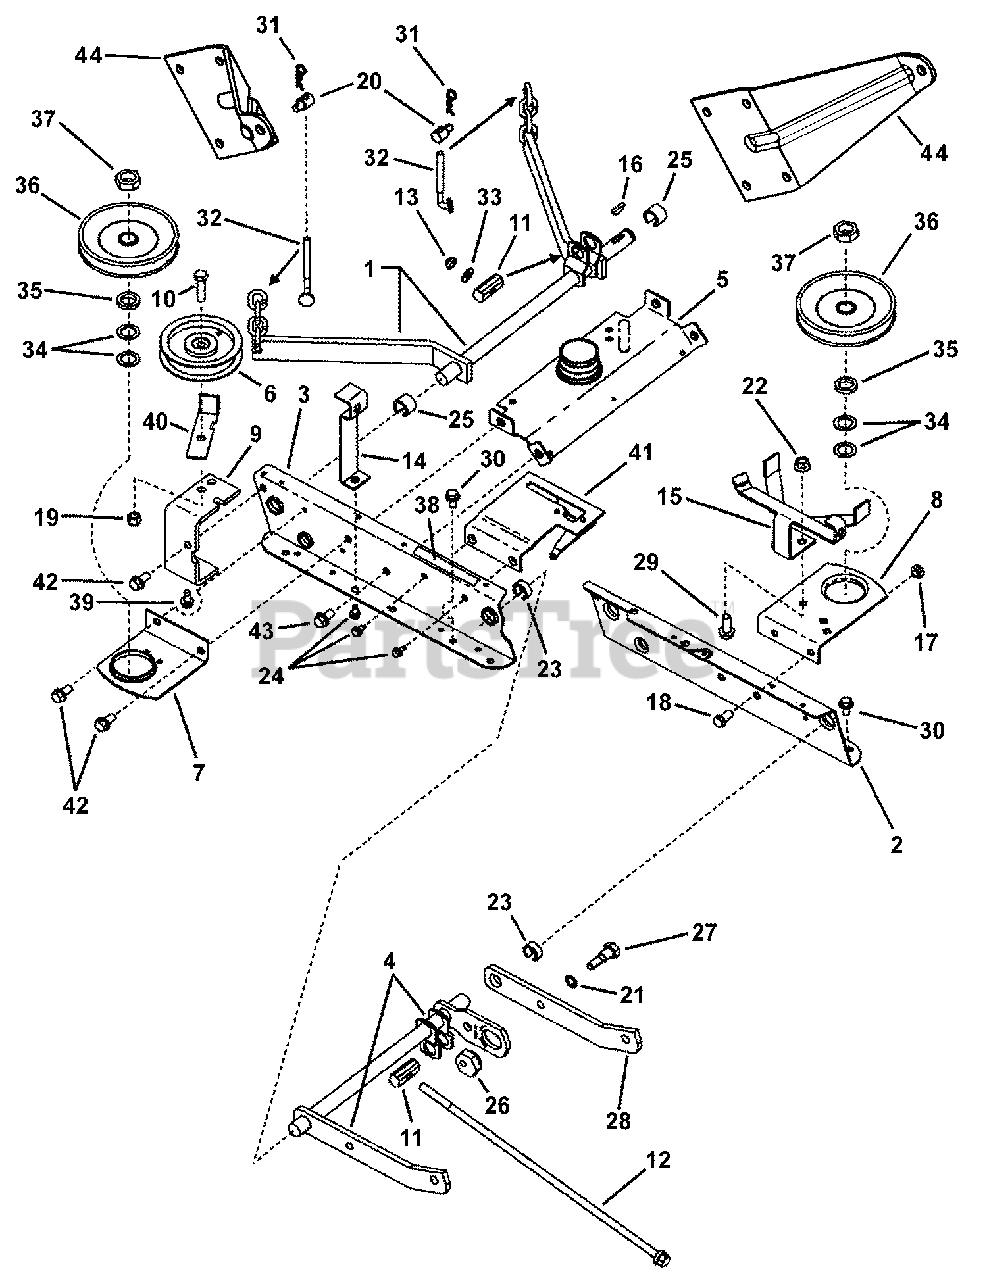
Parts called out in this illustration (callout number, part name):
1	ASSEMBLY, Rear Lift Arm
2	RAIL, Deck Lift, Left Hand
3	RAIL, Deck Lift, Right Hand
4	WELDMENT, Front Lift Arm
5	WELDMENT, Top Brace
6	IDLER, 4-1/8" Flat
7	BRACE, R.H. Spindle
8	BRACE, L.H. Spindle
9	BRACE/IDLER Mounting Bracket
10	SCREW, 3/8-16 x 1-1/2" Hex Head Cap, GR 5
11	PIVOT, Leveling
12	ROD, Leveling
13	NUT, 3/8-16 Hex Top Lock
14	BELT GUIDE, 42"
15	GUIDE, Belt, 42" RER (weldment)
16	KEY, 3/16 x 7/8" Woodruff
17	NUT, 3/8-16 Hex Center Lock
18	SCREW, 3/8-16 x 3/4" Hex Head Cap, GR 5
19	NUT, 3/8-16 Hex Nyloc
20	SWIVEL, Adjustment (with 5/16-18 internal thread)
21	WASHER, 3/8" Internal Tooth Lock
22	NUT, 3/8-16 Hex Flange Lock
23	RING, Front Lift Arm (Red)
24	SCREW, 5/16-18 x 1/2" Hex Washer Self-Tap
25	RING, Rear Lift Arm (Blue)
26	ECCENTRIC, Leveling
27	BOLT, 3/8-24 x 3/4" Shoulder, GR 5
28	ARM, Front Lift (Left Side)
29	BOLT, 3/8-16 x 1" Hex Flange Lock, GR 5
30	BOLT, 5/16-18 x 5/8" Hex Flange Lock
31	HAIR PIN, 3/32 x 1-1/2"
32	ADJUSTER, Chain (5/16-18 thread)
33	WASHER, 3/8" SAE Flat
34	WASHER, .77 x 1.13 x .06 Flat
36	PULLEY, 5" Outside Diameter
37	NUT, 3/4-16 Hex Jam, GR 8
38	DECAL, Blade Engagement, 42" Deck
39	SCREW, 5/16-18 x 5/8" Hex Washer Self-Tap
40	BELT GUIDE
41	ASSEMBLY, Clutch Plate
42	SCREW, 3/8-16 x 3/4" Hex Washer Self-Tap
43	SCREW, 3/8-16 x 5/8" Hex Washer Self-Tap
44	WING, Rear
